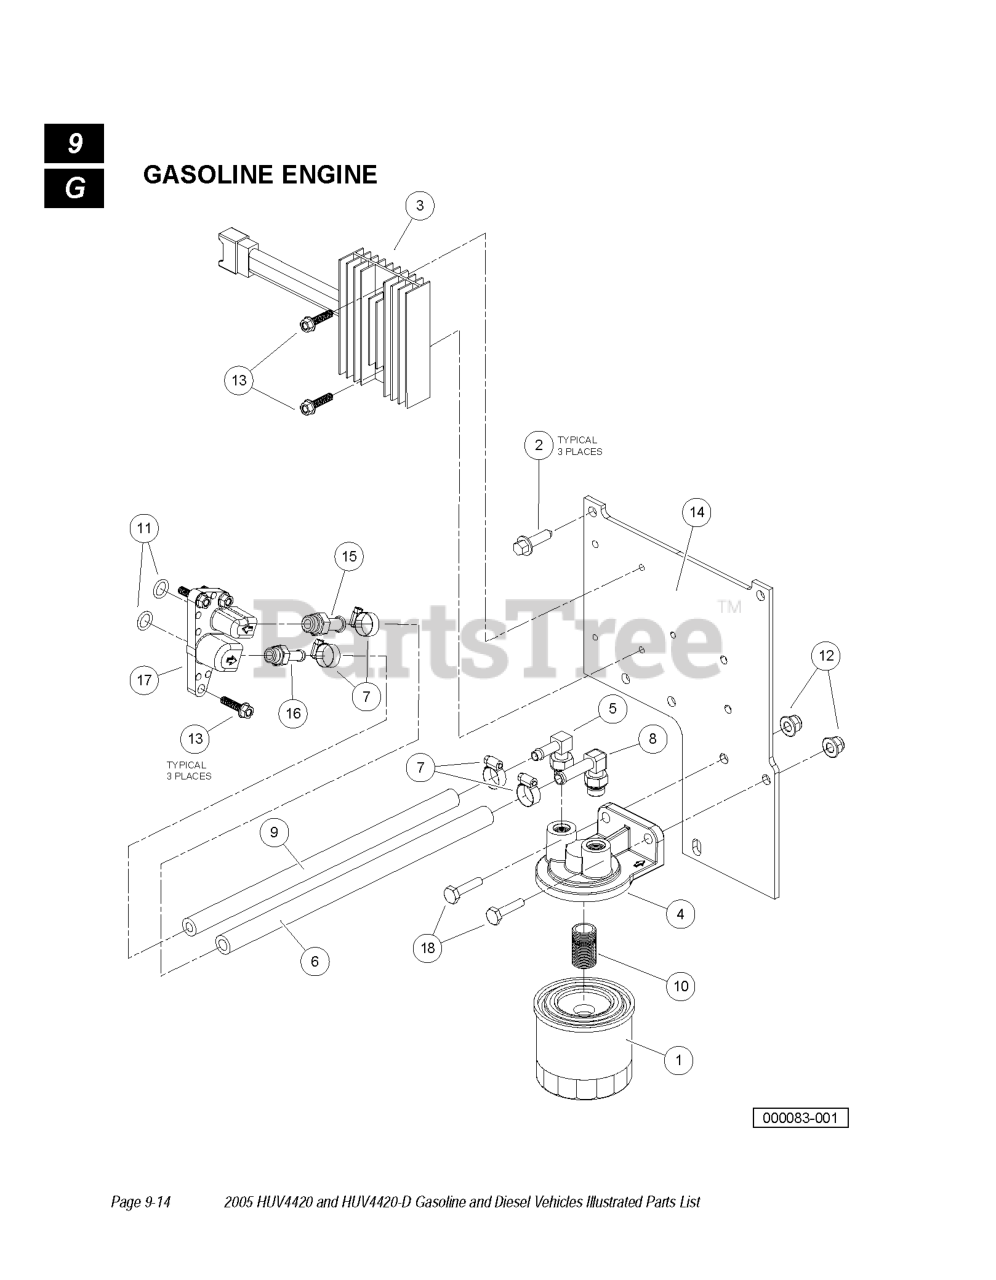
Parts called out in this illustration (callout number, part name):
1	FILTER, OIL
2	SCREW-M8 X 1.25 30, TRI, HX F
3	REGULATOR, VOLTAGE, GX620
4	BRACKET, OIL FILTER MOUNT
5	ADAPTER, 90-5 ORB, 5/16 TUBE
6	HOSE, 3/8 REMOTE OIL, HONDA
7	CLAMP, HOSE #4
8	ADAPTER, 90-6 ORB, 3/8 TUBE
9	HOSE, 5/16, REMOTE OIL, HONDA
10	NIPPLE, M20, REMOTE OIL
11	O-RING 11.8 X 2.4
12	LOCK NUT, FLG M8 X 1.25 NYLON
13	SCREW, M6 X 1 X 25 THD FORM
14	PLATE, FUEL/OIL SYSTEM
15	ADAPTER, ORS -6, 3/8 HOSE, ST
16	ADAPTER, ORS -5, 5/16 HOSE, ST
17	ADAPTER, OIL FILER, ENG HONDA
18	BOLT, M8 X 1.25 X 30
